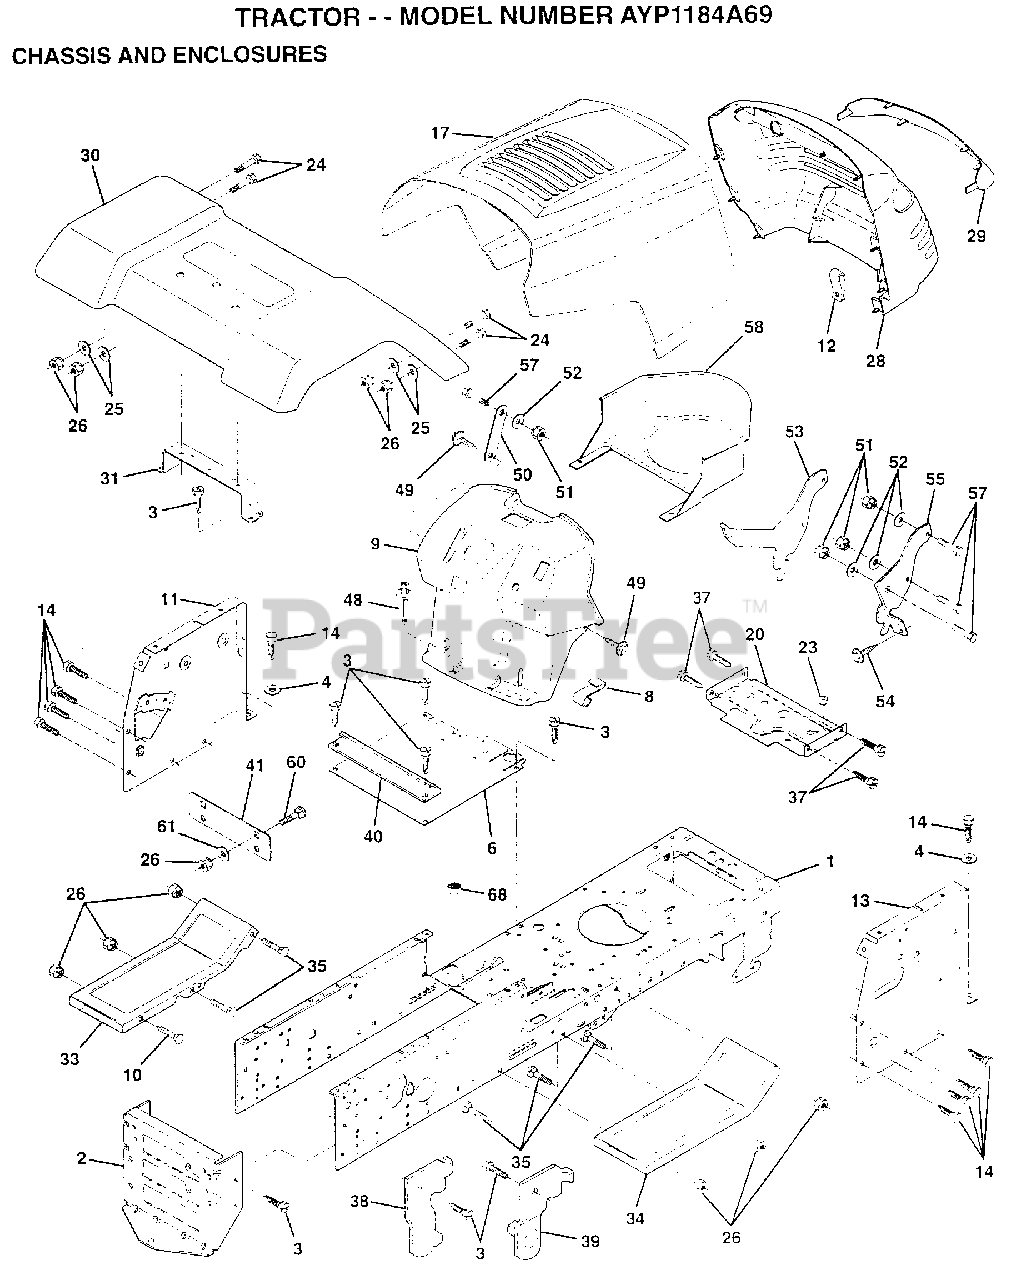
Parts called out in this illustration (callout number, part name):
1	CHASSIS.WLD.11GA
3	SCREW
4	WASHER
8	"CLIP,INSULATOR"
11	PANEL.DASH.LH.
12	CLIP.TINNERMAN
13	PANEL.DASH.RH
14	SCREW LT
24	BOLT
25	WASHER
26	NUT
28	GRILL.BLK
29	LENS GRILLE
30	FENDER
31	BRACKET SUPT FEND
33	FOOTREST LH
34	FOOTREST RH
35	BOLT
37	SCREW LT
37	BRACKET ASM RH
38	BRACKET ASM LH
40	SPACER FENDER LT
41	PLATE EXTEN FEND
48	RIVET.PUSH.PLATE
49	SCREW HEX CRT
50	BRACE SUPT DASH
51	NUT
52	WASHER
53	BRACKET.GRILLE.LH
55	BRACKET.GRILLE.RH
58	DUCT.AIR.B&S.18HP
60	BOLT
61	WASHER
68	NUT
